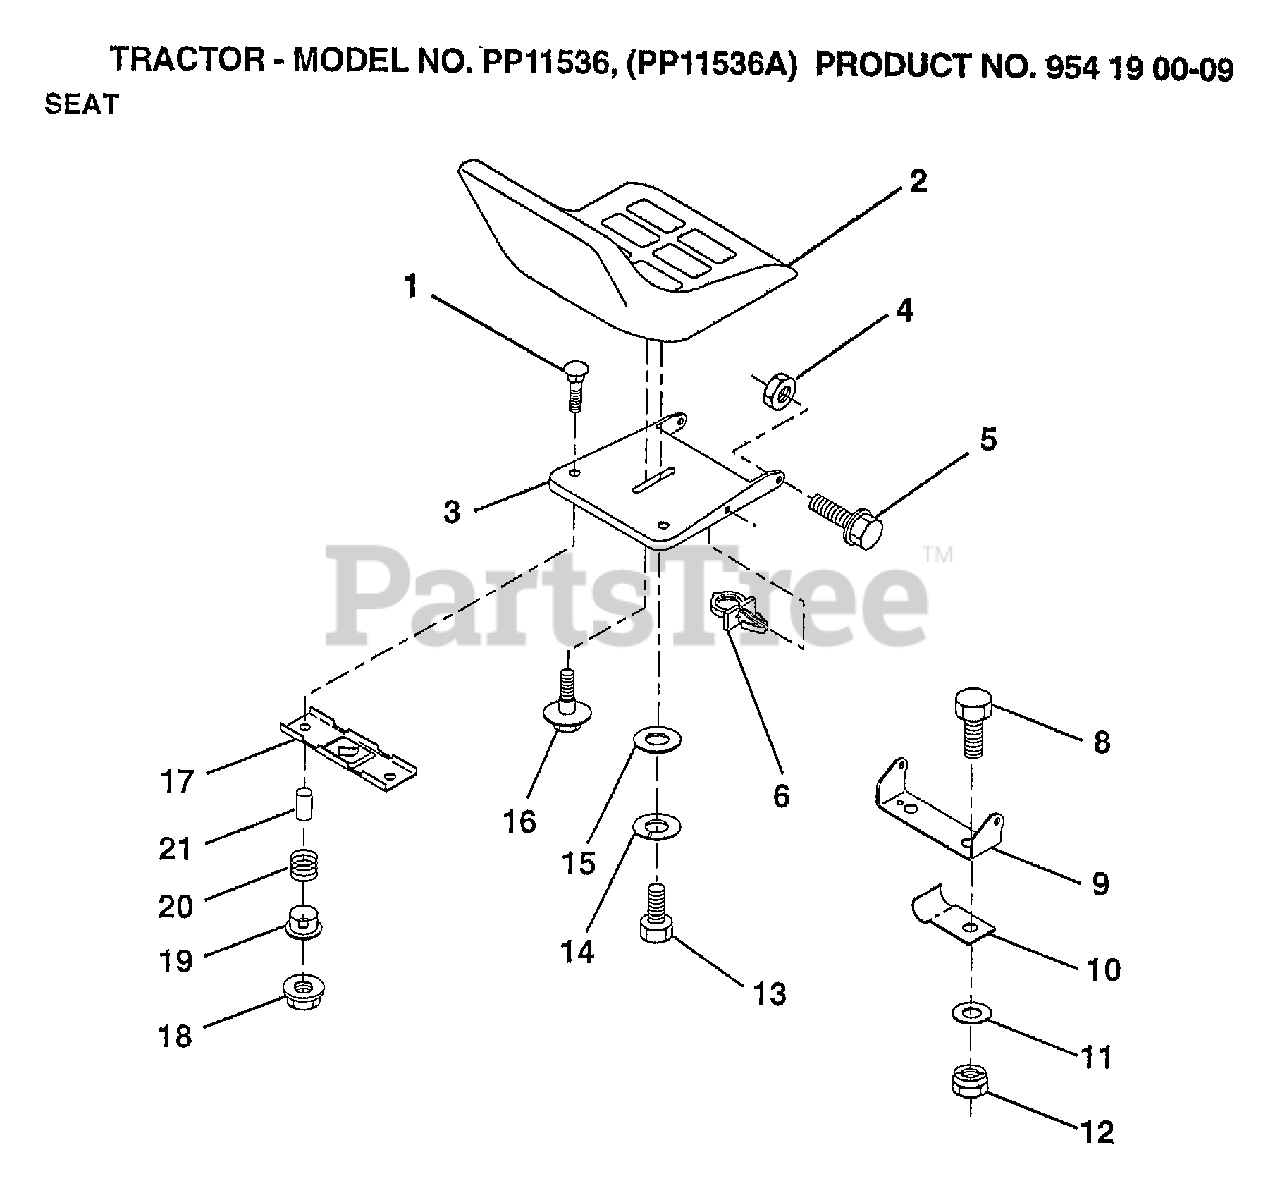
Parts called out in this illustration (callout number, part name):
2	SEAT
3	PAN-SEAT
4	NUT
5	"BOLT,SHOULDER"
6	CLIP.PUSH-IN.HING
8	BOLT
9	BRACKET PVT SEAT
10	"CLIP,INSULATOR"
11	WASHER
12	NUT
13	BOLT
14	LOCKWASHER
15	WASHER
16	"BOLT,SHOULDER"
17	BRKT SWITCH
19	BUSHING
20	SPRING
21	SPLIT SPACER
